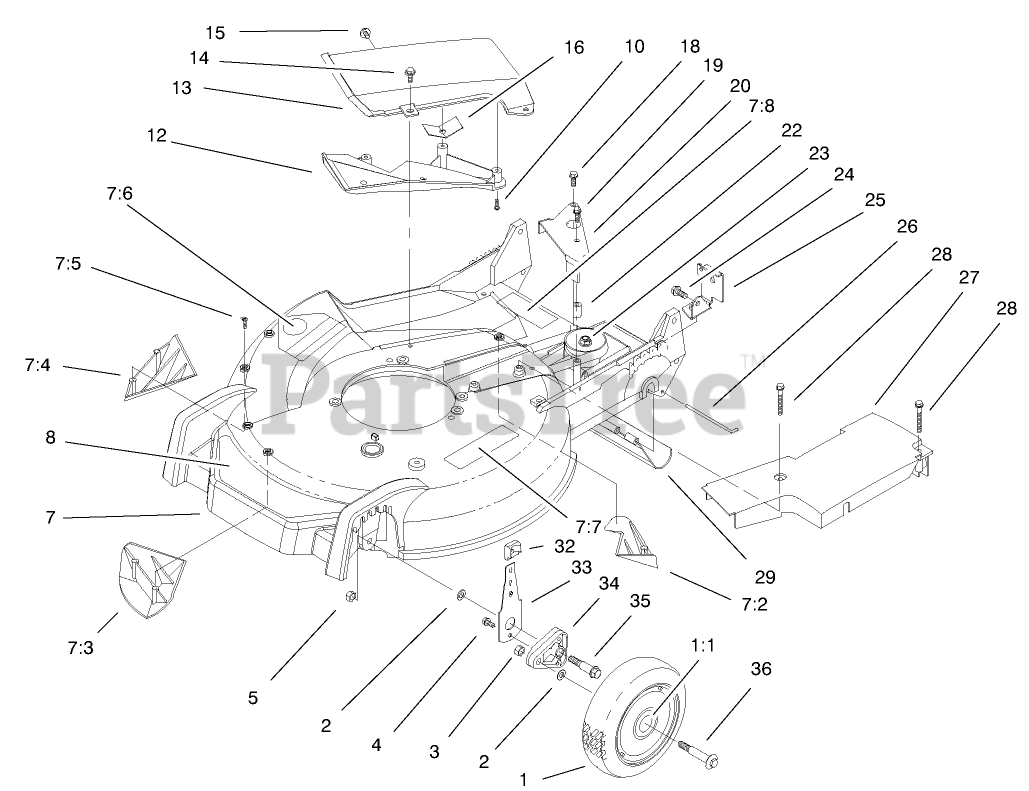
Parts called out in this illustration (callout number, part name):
1	WHEEL ASM
1:1	BUSHING
2	WASHER
3	LOCKNUT
4	SCREW-HWH
5	NUT-LOCK
7:2	KICKER-REAR
7:3	KICKER-FRONT
7:4	KICKER-RH
7:5	SCREW-PPH
7:6	DECAL-DANGER
7:8	DECAL-WARNING
8	DECAL-DECK
13	RECYCLER COVER ASM
13:2	SCREW-PPH
14	SCREW-HWH
15	SCREW AND WASHER ASM
16	SAFETY ISSUE, ORDER COVER ASM
18	SCREW-HWHTF
19	SCREW-HWHTF
20	BRACKET-TRANSMISSION ACTUATOR
22	BUSHING-PLATE, ACTUATOR
23	GEAR CASE ASM
24	SCREW-HWHTF
25	BRACKET-CABLE, TRACTION
26	ROD-SHIELD
27	COVER-BELT
28	SCREW-HWH
32	KNOB-ARM
33	FRONT SPRING ARM ASM
34	ARM-PIVOT, FRONT
35	BOLT-SHOULDER
36	BOLT-SHOULDER
